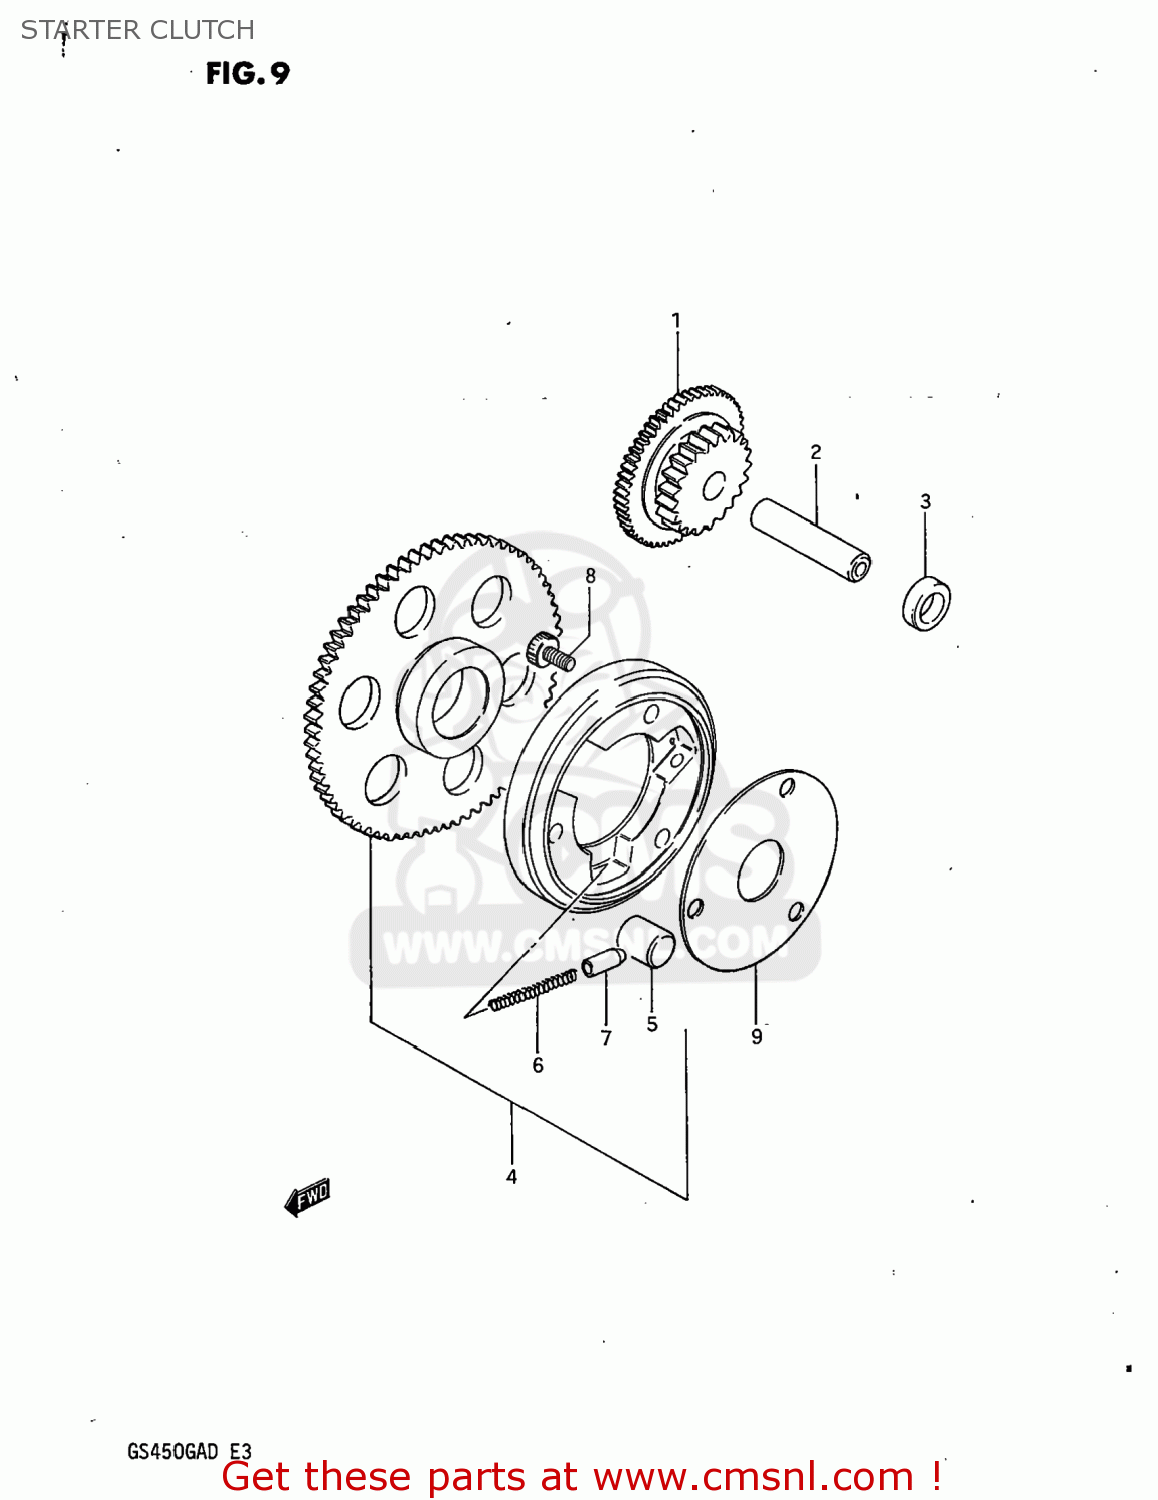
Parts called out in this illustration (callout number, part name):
1	GEAR,STARTER IDLE
2	PIN(7.4X13X56)
3	SPACER
4	CLUTCH SET,STARTER
5	ROLLER(15X13)
6	SPRING
7	PIECE,PUSH
8	BOLT
9	SHIM,STARTER CLUTCH HUB
